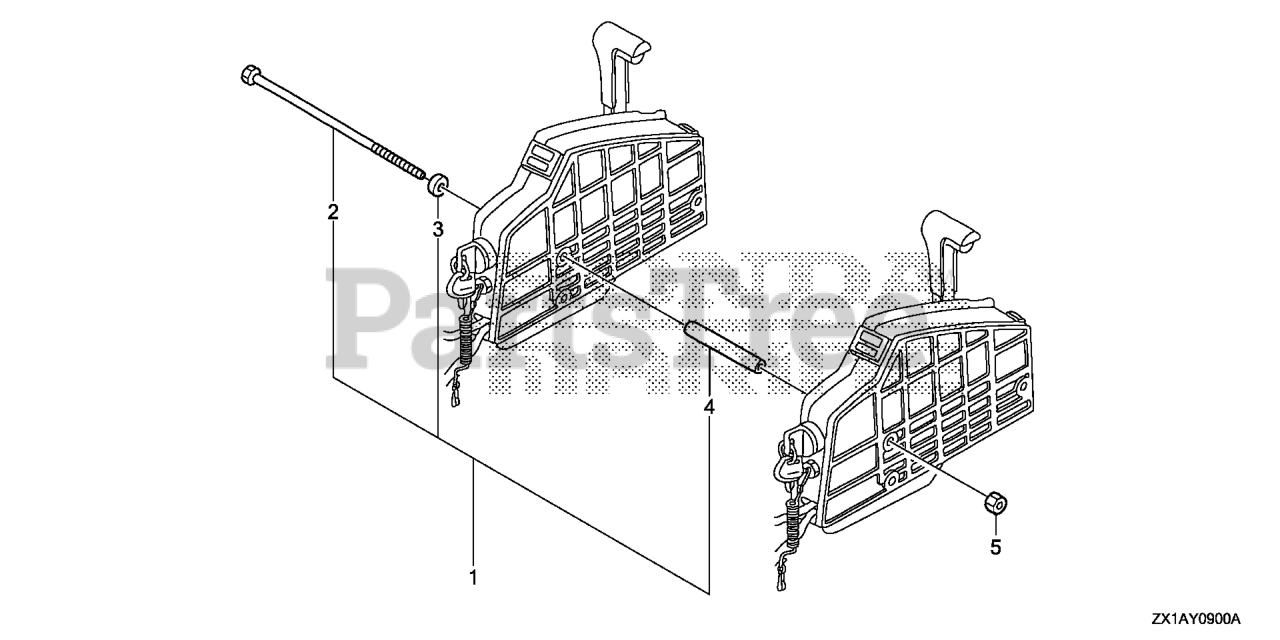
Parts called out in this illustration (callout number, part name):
1	BOLT KIT, SIDE REMOTE CONTROL
2	BOLT, SPECIAL (6X220)
3	COLLAR, DISTANCE (A)
4	COLLAR, DISTANCE (B)
5	NUT, HEX. (6MM)
